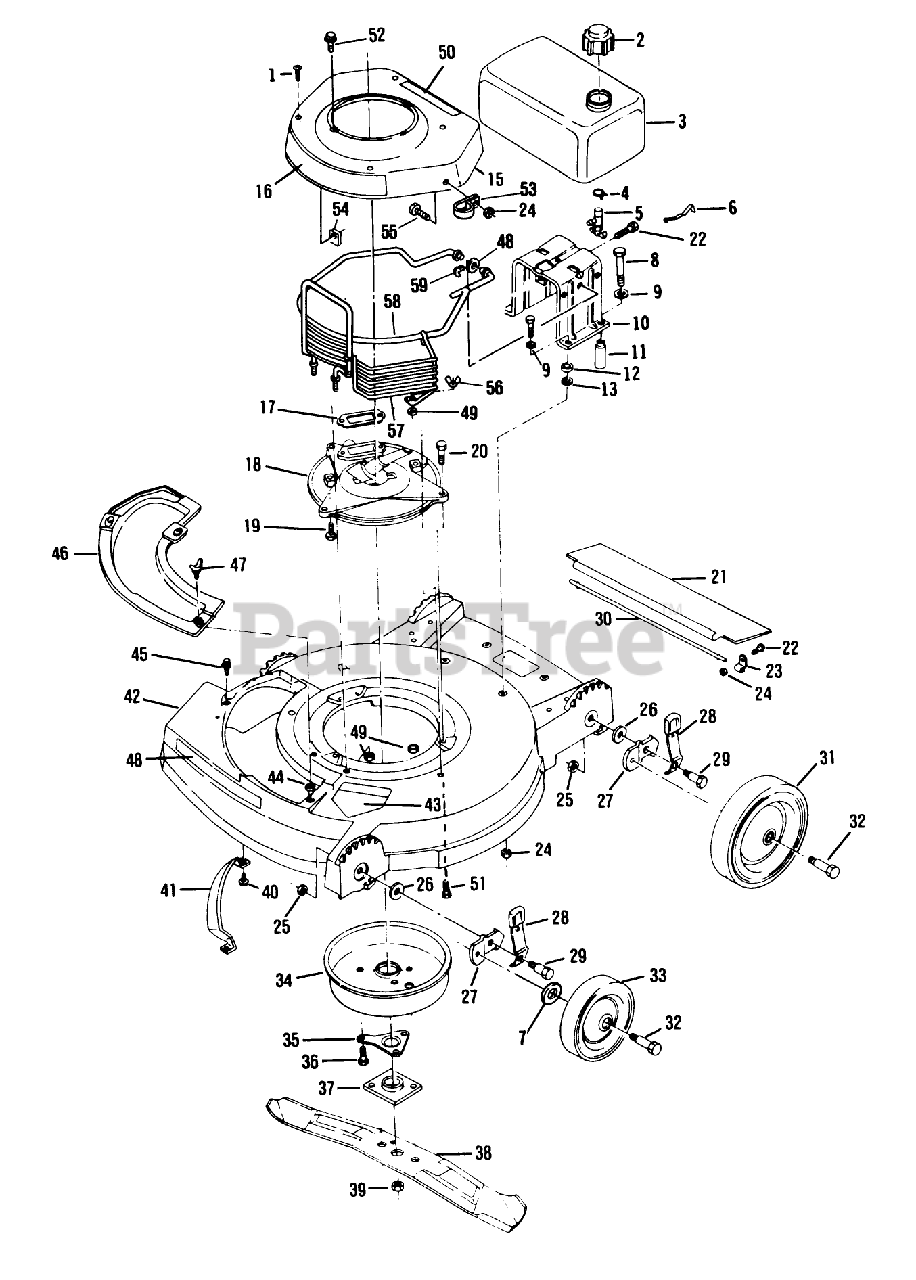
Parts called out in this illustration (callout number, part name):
1	SCREW - SELF TAPPING
2	FUEL CAP & INSERT
4	CLAMP - HOSE S
5	VALVE&SCREEN SM
6	SPRING
7	WASHER WROUGHT
9	WASHER
13	WASHER
14	BOLT PIONEER
18	PLATE F
19	SCREW V
20	SCREW-HH
21	T/SHIELD GEAUGA
23	CLAMP ROD KMC
24	LOCKNUT E
25	LOCKNUT
26	WASHER
28	SPRING ARM ASM
29	BOLT
30	ROD 21" ADVANCE
32	BOLT-SHOULDER
33	WHEEL & TIRE ASSY
34	MUFFLER COVER F
35	SUPPORT F
36	SCREW
37	PLATE AND COLLAR ASM
39	NUT-BLADE
41	BAR-TOE
47	WING SCREW LAWRE
48	WASHER SPRING LAR
49	NUT-LOCK F
51	Screw
52	SCREW SEMS SM
54	PUSHNUT F
59	HAIR PIN
